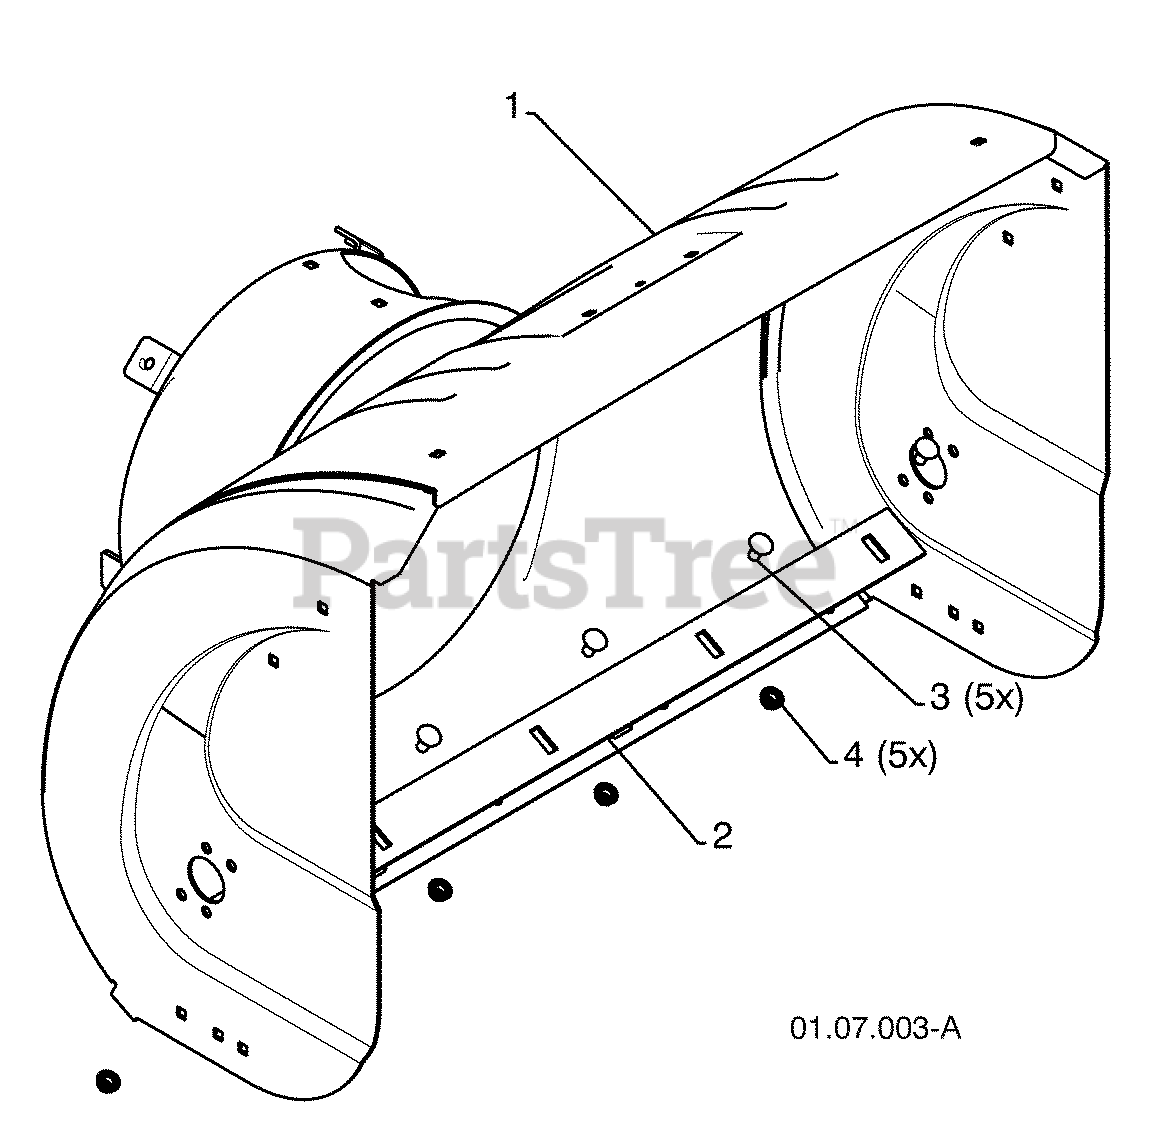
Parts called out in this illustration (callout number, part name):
1	AUGER HOUSING
2	SCRAPPER BAR
3	CARRIAGE BOLT 5/16-18 X .625
4	NUT 5/16-18
